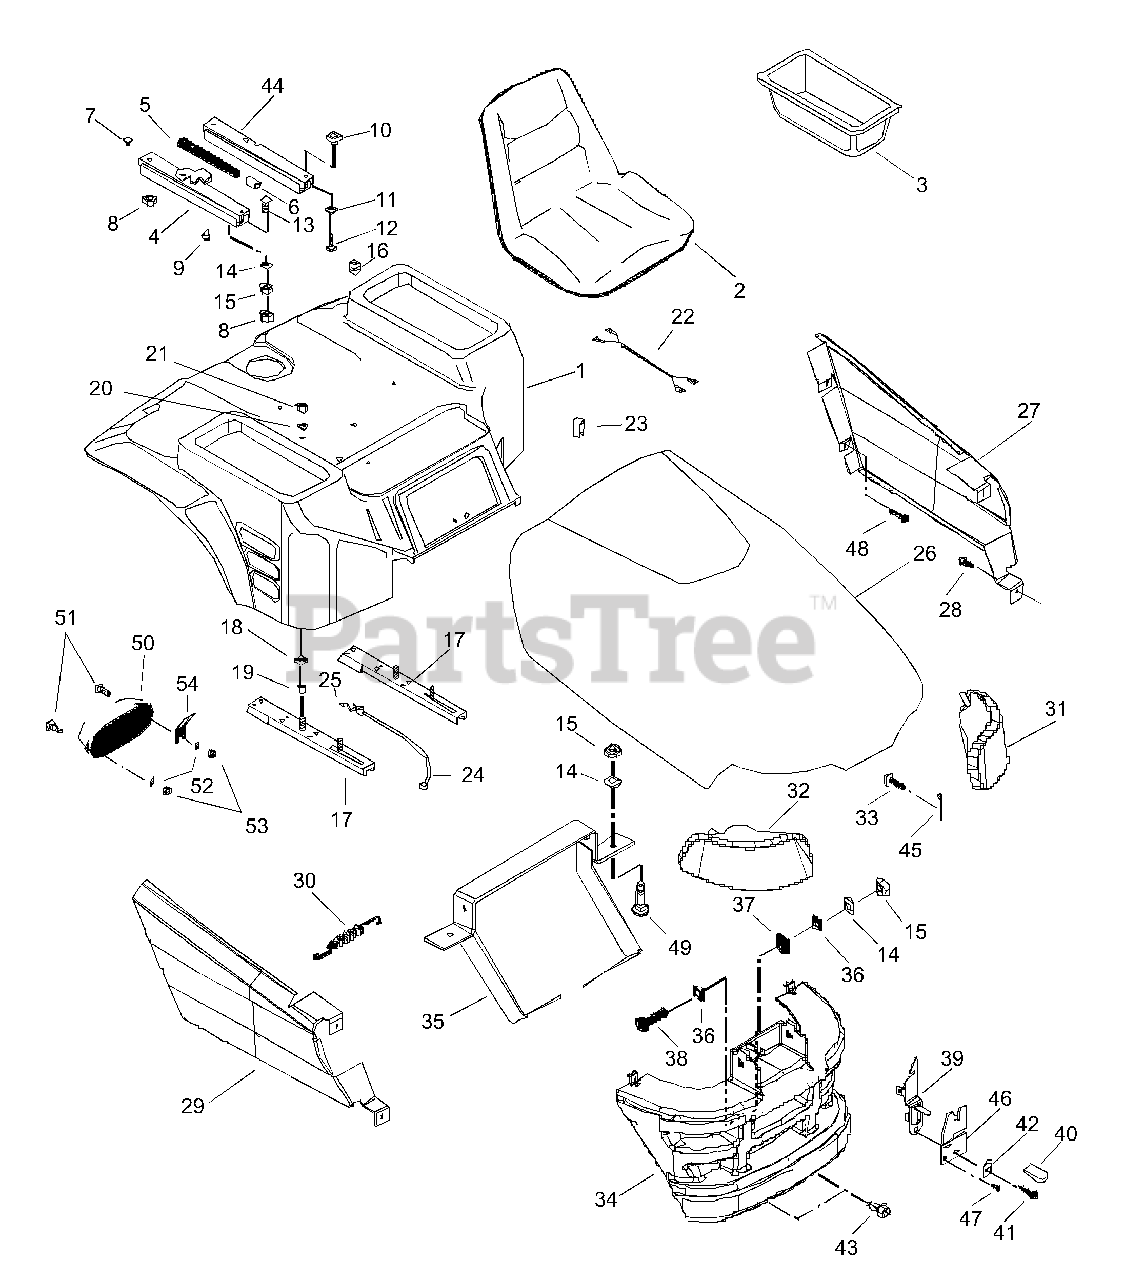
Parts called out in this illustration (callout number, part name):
1	Rear Deck
2	Seat V-850
3	Tray
4	Seat Slide Right Hand
5	Seat Slide Handle
6	Grip
7	Screw-Cap Button Head .31-18 x .50
8	Nut-Locking-Center .31-18
9	Rivet-Pop .187 x .562
10	Seat Slide Spacer
11	Washer-Lock External .326 x .599 x .031
12	Screw-Machine .31-18 x 1.00
13	Screw-Cap .31-18 x .75
14	Washer-Lock .312 x .097
15	Nut-Hex .31-18
16	Grommet .188 x .375
17	Seat Support
18	Washer-Flat-Steel .390 x .75 x .125
19	Spacer .380 x .503 x .281
20	Washer-Lock .38 x .094
21	Nut-Hex .38-16
22	Seat Harness
23	Wire Clip
24	Cable
25	Steel Hook
26	Hood with Decals
27	Side Panel - Left Hand
28	Screw-Tapping 12-16 x .500
29	Side Panel - Right Hand
30	Spring - Tension .035 x .45 x 2.75
31	Headlight - Left Hand
32	Headlight - Right Hand
33	Clevis Pin .243/.248 x 1 1/2
34	Grille
35	Mount-Grille
36	Washer .328 x 1.0 x .094
37	Washer-Flat-Nylon .375 x 1.000 x .062
38	Bolt-Hex .31-18 x 1.00 Grade 5
39	Hood Latch
40	Grip .062 x .375 x .750
41	Screw-Tapping 12-24 x .50
42	Washer-Flat-Steel .281 x 1.250 x .048
43	Screw-Tapping .31-18 x .75
44	Seat Slide Left Hand
45	Pin-Cotter .09 x .75
46	Locator-Hood
47	Screw-Tapping 10-12 x .50
48	Screw-Tapping 10-16 x .62
49	Bolt-Round Head Square Neck .38-16 x 1.0
50	Tail Light Assembly
51	Screw-Machine 10-24 x .50 Slotted Round Head
52	Washer-Lock #10 x .047
53	Nut-Hex 10-24
54	Male Disconnect Adapter
